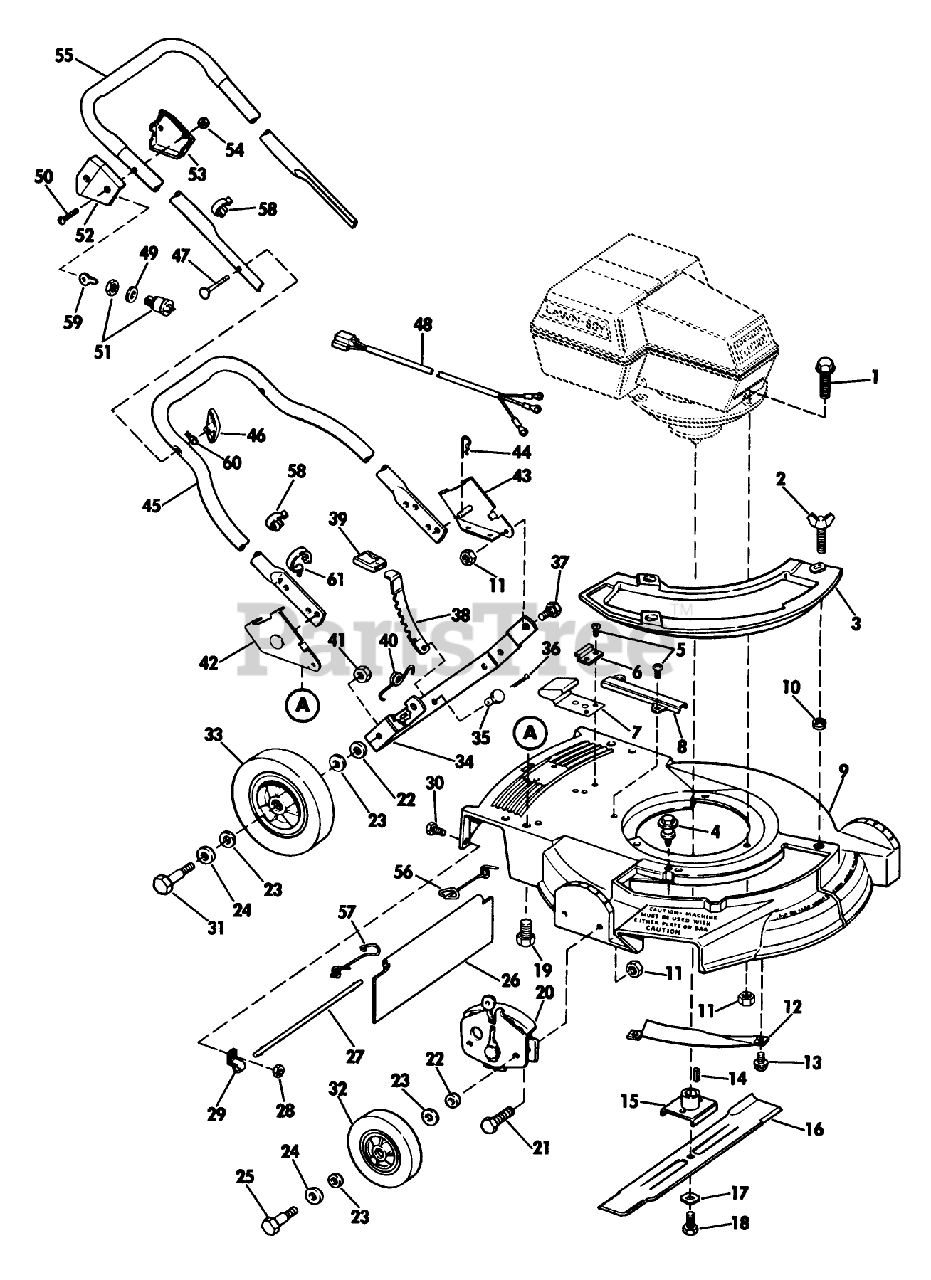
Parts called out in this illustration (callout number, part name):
1	SCREW
2	WING SCREW LAWRE
11	NUT-LOCK F
12	TOE BAR 19"
16	19" Blade
19	SCREW
22	WASHER WROUGHT
23	WASHER
24	SPACER
25	BOLT WHEEL
26	TRAILING SHIELD-19
27	ROD T/SHIELD ADV WIRE
28	LOCKNUT E
29	CLAMP ROD KMC
31	BOLT
35	PIN
37	BOLT-SHOULDER
39	KNOB
40	SPRING N.A.S
41	LOCKNUT
44	HAIR PIN
46	NUT-WING
52	SWITCH HOUSING
54	NUT S
56	SPRIG T/SHLD ASOC
57	SPRING;TRAILING SHIELD RH
61	RETAINER ARDEN
